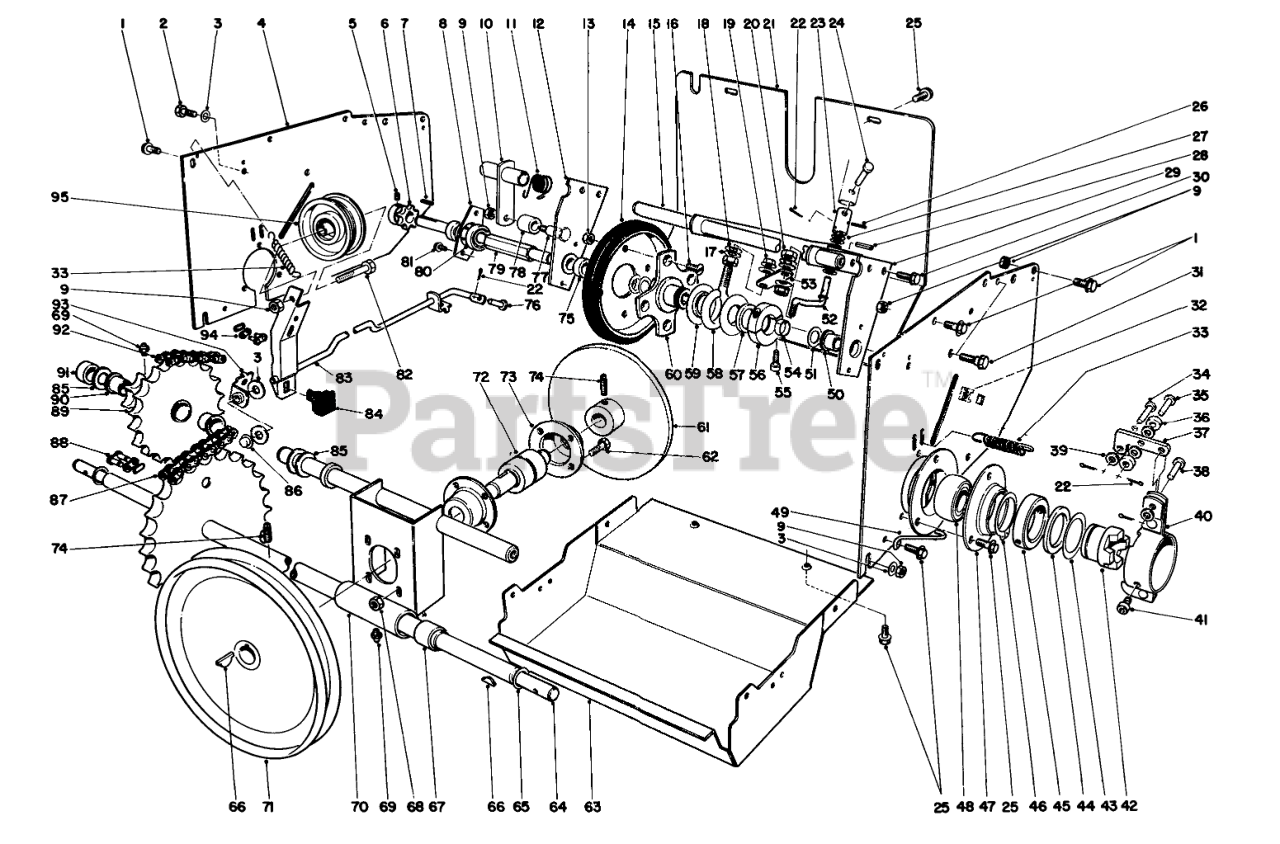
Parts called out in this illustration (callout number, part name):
1	SCREW-HH
2	SCREW-HHFTF
3	WASHER-FLAT
4	Side Plate Drive
5	SCREW-HSH
6	SPROCKET
8	BEARING CUP
9	NUT-HEX
10	CHAIN TENSION ARM WA
11	TORSION SPRING
12	HEX SHAFT MOUNT R
13	Nut
14	FRICTION WHEEL
15	Bracket Dead Shaft
16	5/16-18X5/8 FLT HD MS
17	WASHER-FLAT
18	WASHER-SPRING
19	NUT-LOCK, FLANGE
20	Nut
21	REAR COVER R
22	PIN-COTTER
23	U JOINT TUBE
24	CLEVIS PIN
25	SCREW-HWH
26	PIN-SPRING
27	Clevis Pin
28	PIN-ROLL
29	Hex Shaft Mounting (Incl. Ref. #50)
30	SCREW-HWHTF
31	SHOULDER SCREW
32	RETAINER NUT
33	EXTENSION SPRING
34	PIN-CLEVIS
35	PIN-CLEVIS
36	CLUTCH ROLLER
37	CLUTCH CAM ARM
38	PIN-CLEVIS
39	WASHER-FLAT
40	CLUTCH MT BRKT ASM
41	SCREW-HSH
42	WHEEL CLUTCH
43	THRUST WASHER
44	THRUST BEARING
45	CLUTCH MOUNT COLLAR
46	RING-RETAINING, EXTERNAL
47	BEARING FLANGE
48	BEARING
49	CLUTCH RETAINER
50	BUSHING
51	WASHER-FLAT
52	CONNECTION ROD
53	SHIFT ROD PIVOT
54	SPLIT SPACER
55	SCREW-HSH
56	ColIar
57	WASHER-THRUST
58	SLIDER RING COLLAR
59	SLIDER RING
60	TRACTION DISC HUB
61	FRICTION PLATE O
62	SCREW-HH
63	LOWER SHIELD R
64	AXLE SHAFT WA
65	WASHER
66	KEY-WOODRUFF
67	BUSHING
68	NUT-KEPS
69	FITTING-GREASE
70	Bulkhead (Incl. Ref. #67)
71	Pulley
72	BEARING-FRICTION PLATE
73	HOUSING BEARING
74	SCREW-SET, SQH
75	SPACER
76	PIN-CLEVIS
77	SHOULDER BOLT
78	CHAIN TENSION ROLLER
79	FRICTION WHEEL SHAFT
80	BEARING
81	SCREW
82	SCREW-HH
83	Auger Brake Assembly (Incl. Ref. #84)
84	Brake Pad
85	WASHER-THRUST
86	PUSH NUT
87	ROLLER CHAIN
88	LINK-CHAIN
89	Sprocket (Incl. Ref. #69 & 90)
90	3/4ID X 3/4LG BSHG
91	SPACER-IDLER
92	1/4 X 42 CHAIN W/LINK
93	Bracket-Clutch
94	LINK-CONNECTING
95	PULLEY-IDLER
